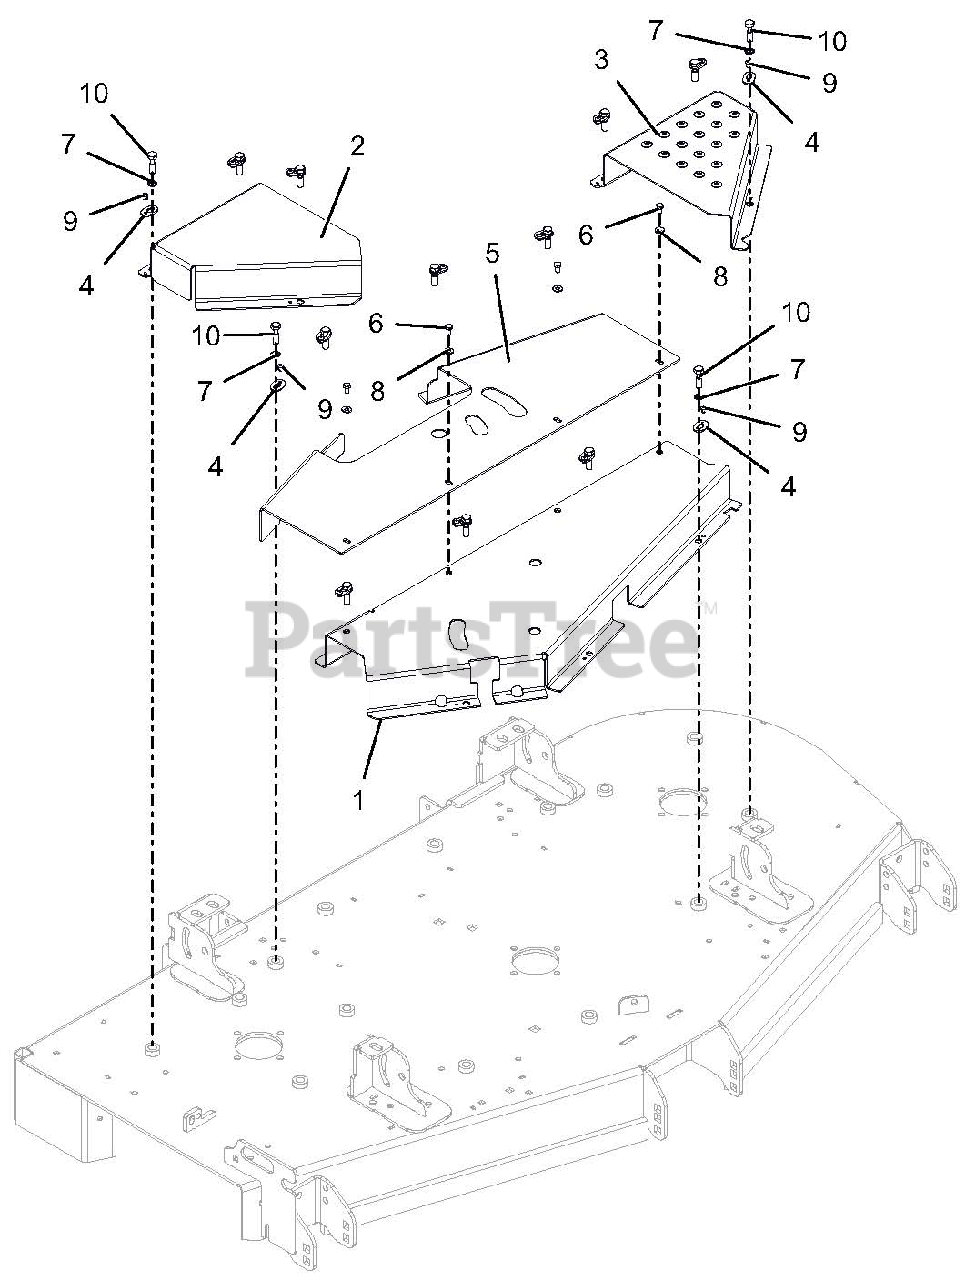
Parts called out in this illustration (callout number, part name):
1	WDMT, FRONT BELT GUARD CE-260
2	GUARD, RH PT200 CE BELT (BLACK)
3	GUARD, LH PT200 CE BELT (BLACK)
4	KEEPER, BOLT
5	GUARD, CE 60" REAR CENTER DECK
6	@BLT-HEX .25-20X.50 GR5 YWZC
7	@WSHR-LK-EXT.391X.628X.036YWZC
8	@WSHR-FL-STL.281X.62X.065 YWZC
9	RVT-POP .187x.250 (#64) YWZC
10	BLT,HEX.38-16X1.25 GR5 CAPTIVE
